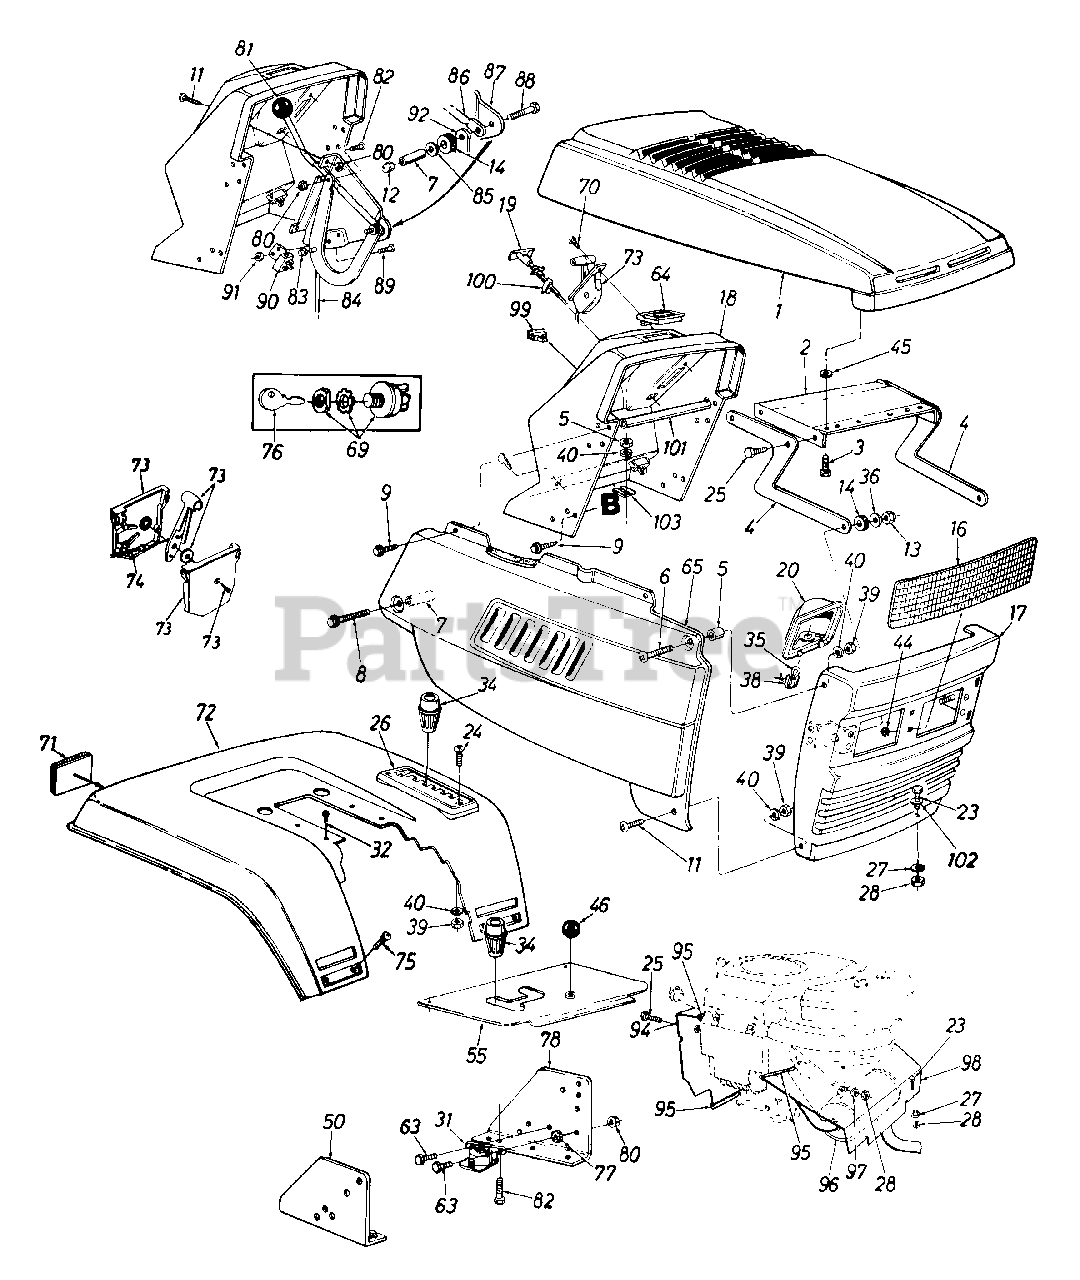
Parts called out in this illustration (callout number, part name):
4	Hood Hinge
5	Spacer .34" I.D. x .437"
6	Truss Hd. Mach. Scr. 1/4-20 Thd.
7	Spacer .26" I.D. x .375"
8	Hex Wash. TT-Tap Scr. 1/4-20 x 1.75" Lg.
9	Hex T-Tap Scr. 1/4-20 x .75" Lg.
11	Truss Mach. Scr. 1/4-20 x .5" Lg.
12	Hex Ins. L-Nut 1/4-20 Thd.
13	Hex L-Nut 5/16-18 Thd.
14	Rubber Washer
16	Headlight Lens
19	Choke Control
20	Headlight Housing
23	Hex Bolt 5/16-18 x .75" Lg.
24	Truss Mach. Scr. 1/4-20 x .75" Lg.
25	Hex Wash. Hd. Scr. 1/4" x .5" Lg.
26	6-Speed Selector Plate
27	L-Wash. 5/16" I.D.
28	Hex Nut 5/16-18 Thd.
31	Solenoid
32	Hex Hd. Rolling Scr. 5/16-24 x .75" Lg.
34	Shift Knob
35	Lamp
36	Bell-Wash. .34" I.D. x .87"
38	Socket
39	Hex Nut 1/4-20 Thd.
40	L-Wash. 1/4" I.D.
44	Speed Nut 5/16" I.D.
45	Fl-Wash. .406" I.D.
46	Ball Knob
63	Hex Bolt 1/4-20 x .5" Lg.
64	Ammeter
70	Truss Mach. AB-Tap Scr. #10 x .5" Lg.
71	Reflector
74	Throttle Control Wire 35" Lg.
75	Carriage Bolt 1/4-20 x .5" Lg.
76	Key
77	Ext. L-Wash. 1/4" I.D.
81	Ball Knob
82	Hex Bolt 1/4-20 x .62" Lg.
83	Push Nut
84	PTO Rod
85	Fl-Wash. .281" I.D. x.73"
86	PTO Lever
87	Deck Clutch Control Brkt.
88	Hex Bolt 1/4-20 x 2.5" Lg.
89	Truss Mach. Scr. #10-24 x .5" Lg.
90	Safety Switch
91	Hex Nut #10-24 Thd.
92	PTO Bracket
94	Engine Baffle
95	Trim Strip 12" Lg.
96	Muffler
97	Spec. L-Wash. 5/16" I.D.
98	Front Heat Shield
99	Light Switch
100	Retainer Clip
101	Dash Support Tube
102	Fl-Wash. .344" I.D. x 1" O.D.
103	Dash Panel Fastening Tab
